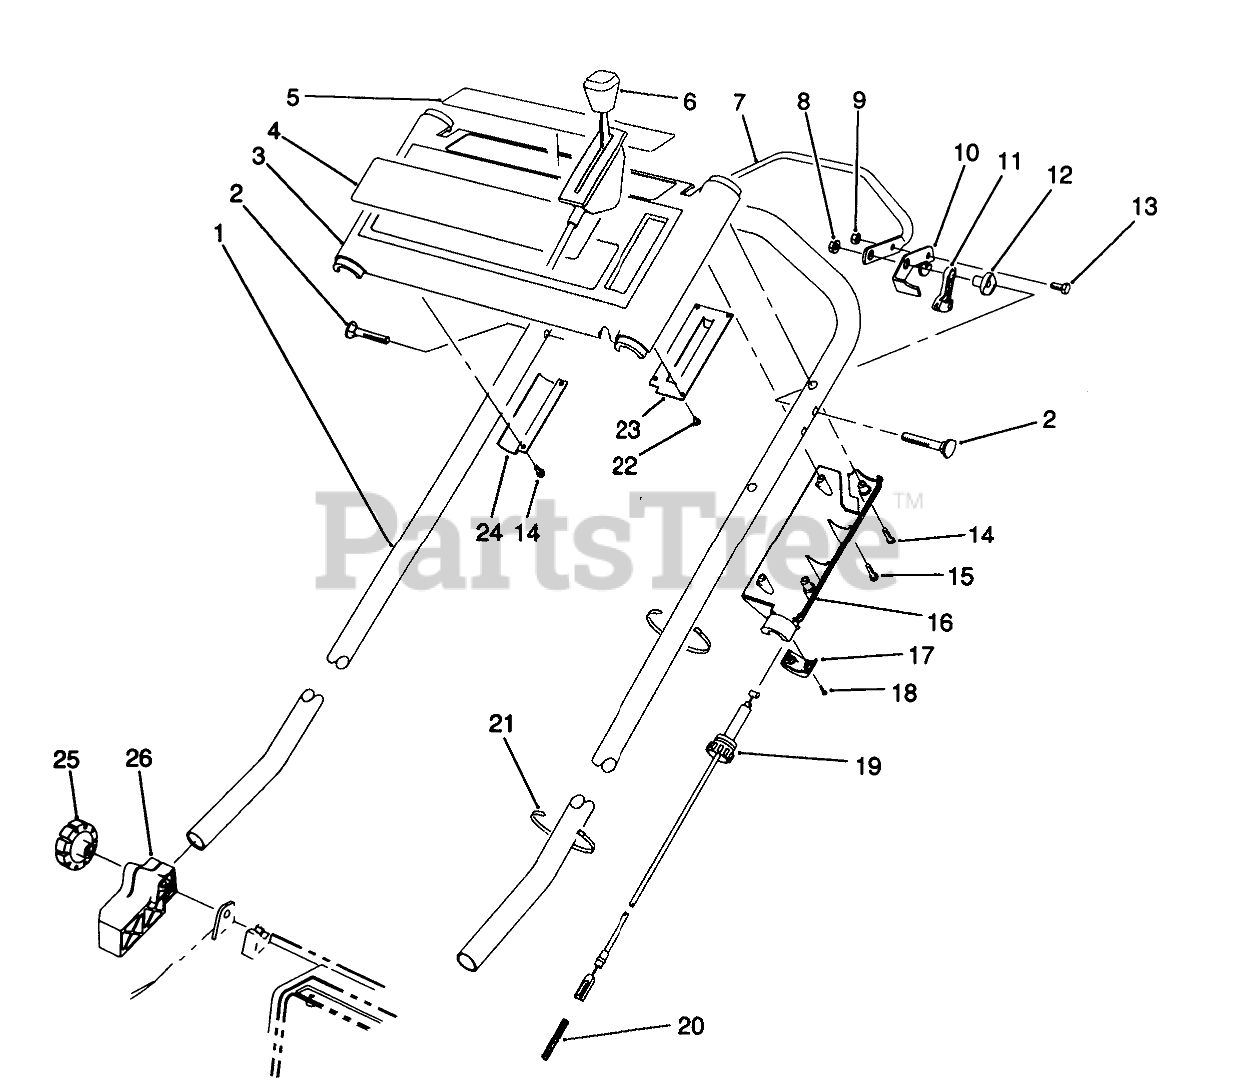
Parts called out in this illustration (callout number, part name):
1	Handle
2	SCREW-HANDLE
3	Panel-Control (Incl. Ref #4, & 5)
4	DECAL - TORO
5	DECAL - PANEL DANGER
6	THROTTLE CONTROL
7	CONTROL BAR
8	NUT-LOCK, NI
9	NUT-LOCK, NI
10	CONTROL LEVER
11	LEVER-TRACTION
12	SPACER-SUPPORT
13	SCREW-HH
14	SCREW-PPH, PLASTITE
15	Screw
16	Cover-Throttle Lower
17	LOWER THROTTLE CAP
18	#4-14X.62 PLASTITE SCW
19	TRACTION CABLE
20	SPRING-COMPRESSION
21	TIE-CABLE
22	#6-19X.25 PLASK FORM SC
23	THROTTLE PLATE
24	Bracket-Panel
26	MOUNT-HANDLE, RH
